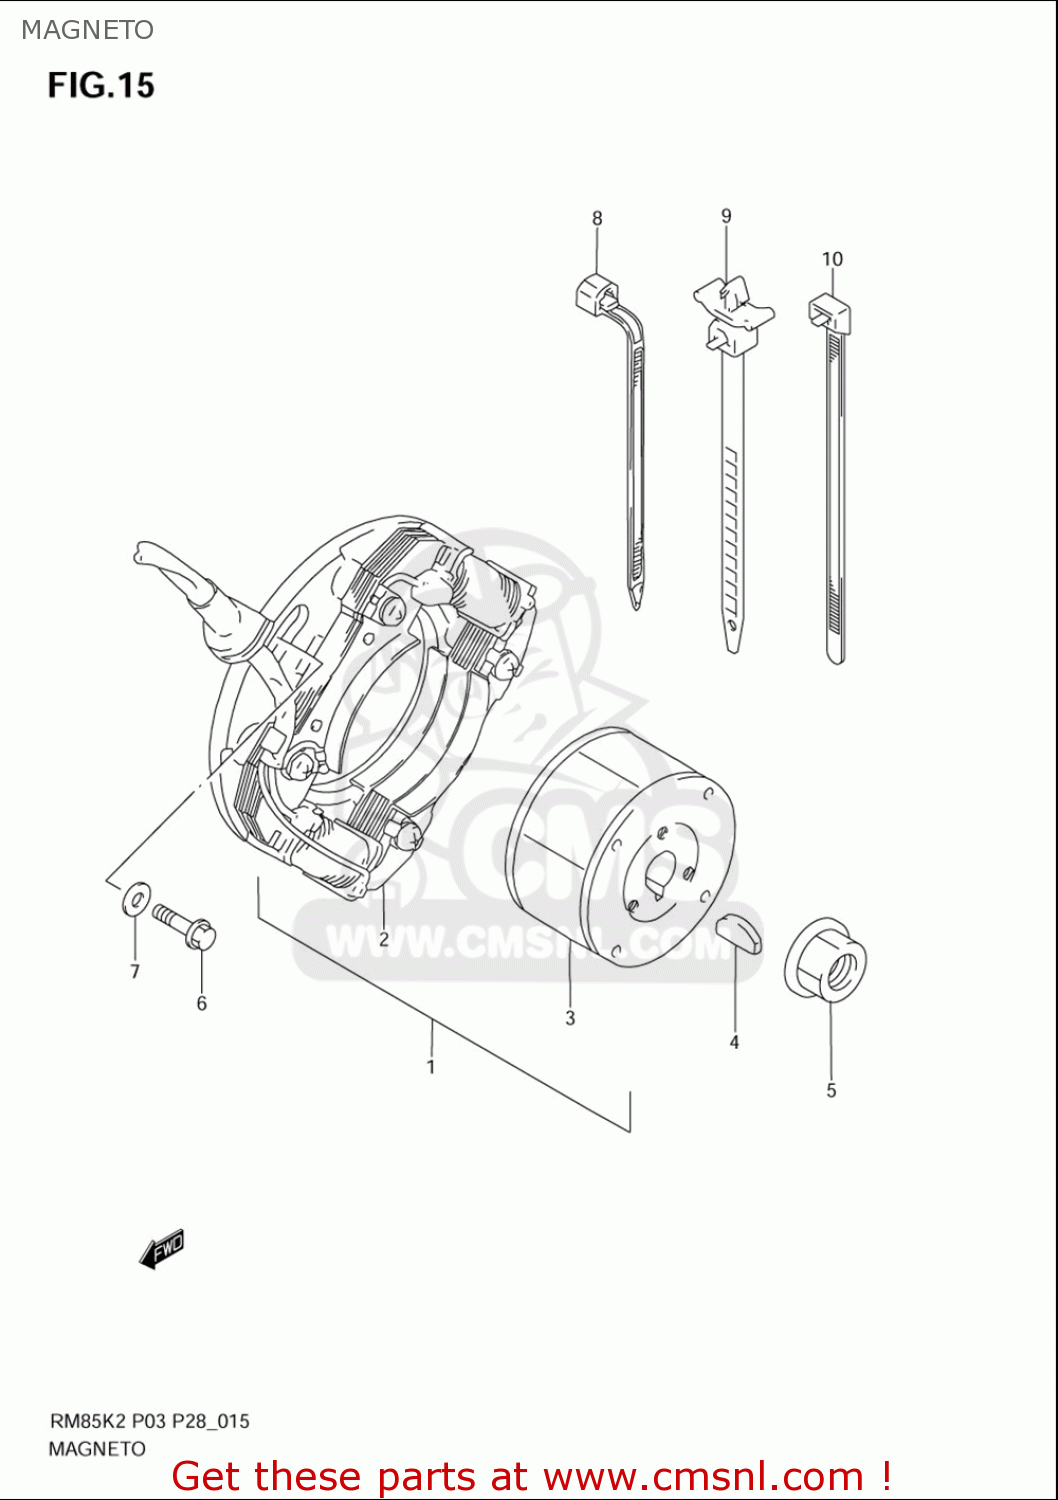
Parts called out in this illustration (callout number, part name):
1	MAGNETO ASSY
2	STARTER ASSY
3	ROTOR
4	KEY
5	NUT
6	BOLT,6X20
7	WASHER
8	CLAMP(L:125)
9	CLAMP
10	CLAMP(L:150)
